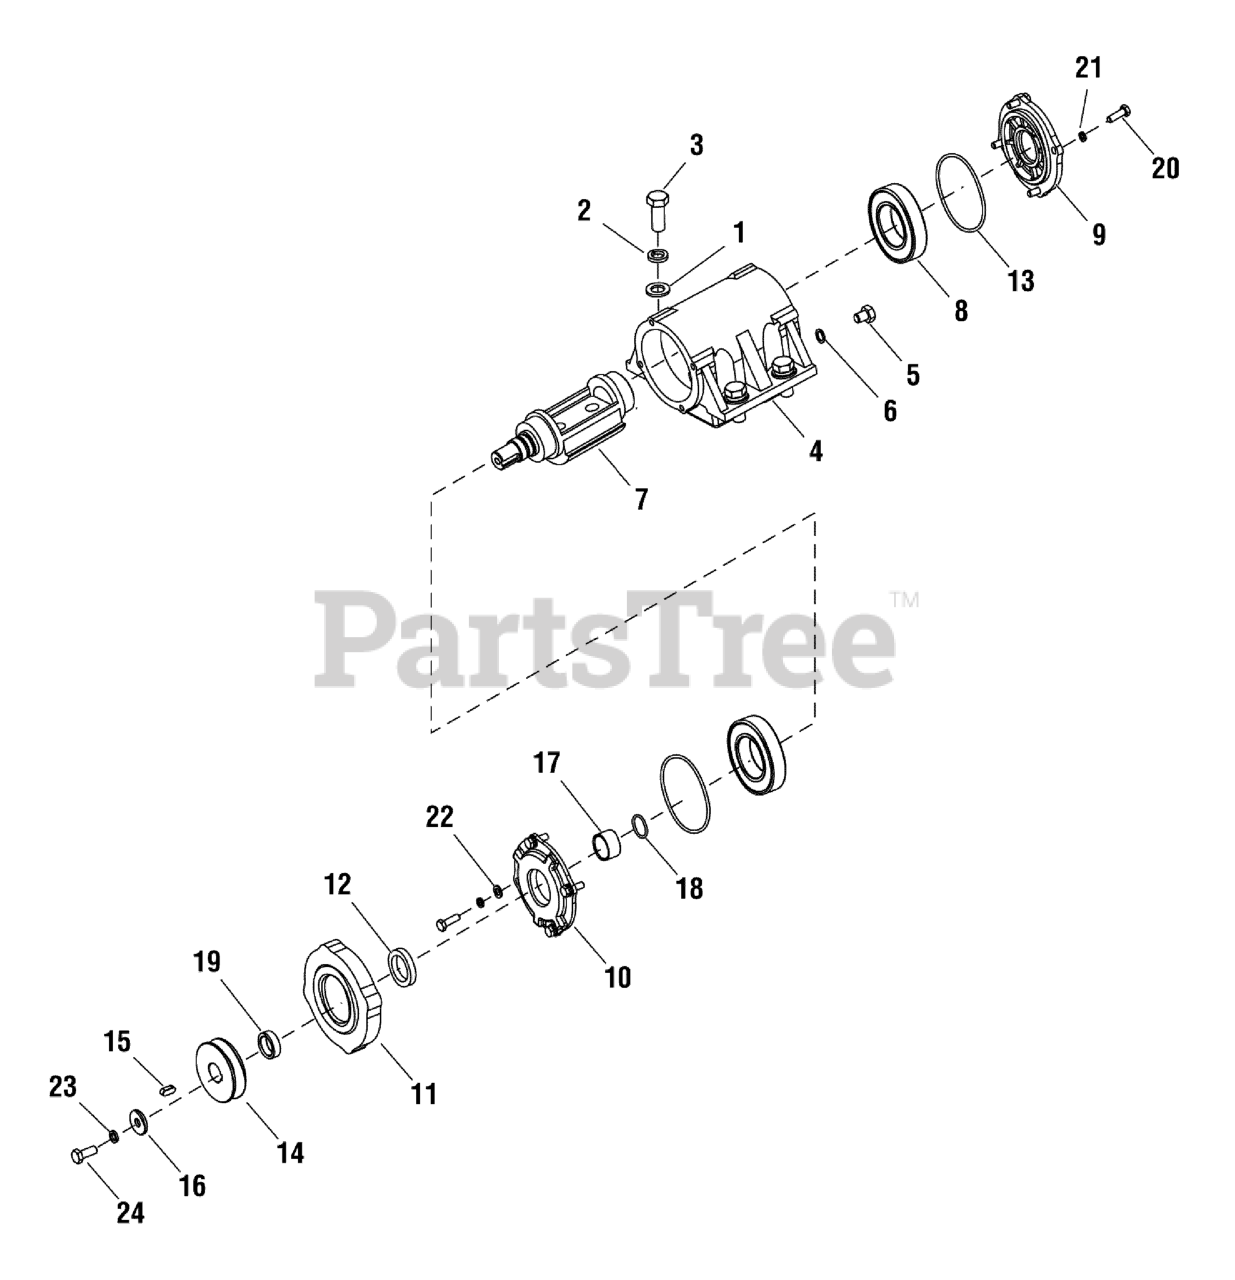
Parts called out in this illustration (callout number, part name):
1	WASHER, Flat
2	WASHER, Spring
3	BOLT, Hex, M16 x 40
4	VIBRATION BOX
5	SCREW, Plug
6	PACKING PIECE
7	ECCENTRIC ROTATOR ASSEMBLY
8	BEARING
9	COVER, Case, RH
10	COVER, Case, LH
11	PROTECTIVE COVER
12	OIL SEAL 35 x 8
13	O-RING
14	PULLEY
15	KEY 8 x 20
16	WASHER, Pulley
17	BEARING
18	O-RING
19	BUSHING, Shaft
20	BOLT, Hex, M8 x 25
21	WASHER, Spring, 8
22	WASHER, Flat, 8
23	WASHER, Spring, 10
24	BOLT, Hex, M10 x 25
